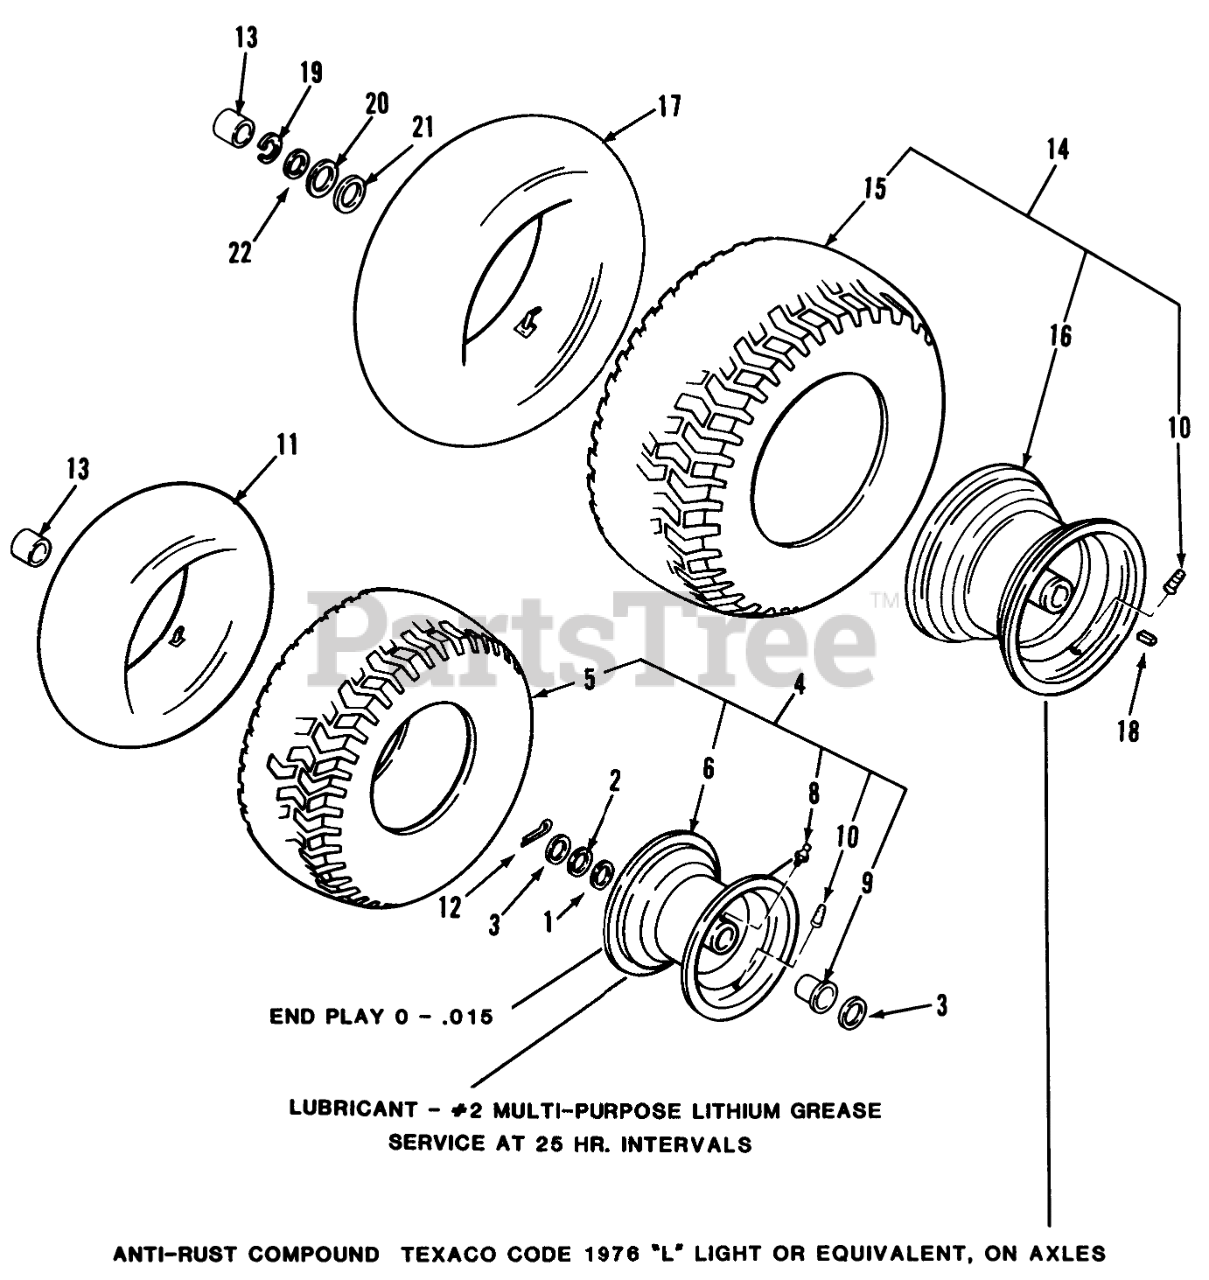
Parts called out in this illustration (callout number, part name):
1	WASHER-SHIM
2	WASHER
3	WASHER-FLAT
4	Front Wheel and Tire 15 x 6.00-6 (Includes items 5, 6, 8, 9 & 10)
5	TIRE-15 X 6.00-6
6	Front Wheel Assembly (Includes Wheel with items 8, 9, & 10)
8	ZERK-GREASE
9	Bearing
10	VALVE
12	COTTER PIN-4
13	HUB CAP
14	Rear Wheel & Tire-212-5
15	TIRE-18X9.50-8 TT RS
16	Rear Wheel 212-5
17	Tube-Inner
18	SQ KEY
19	E Ring
20	WASHER-SHIM
21	WASHER
22	WASHER-FLAT
